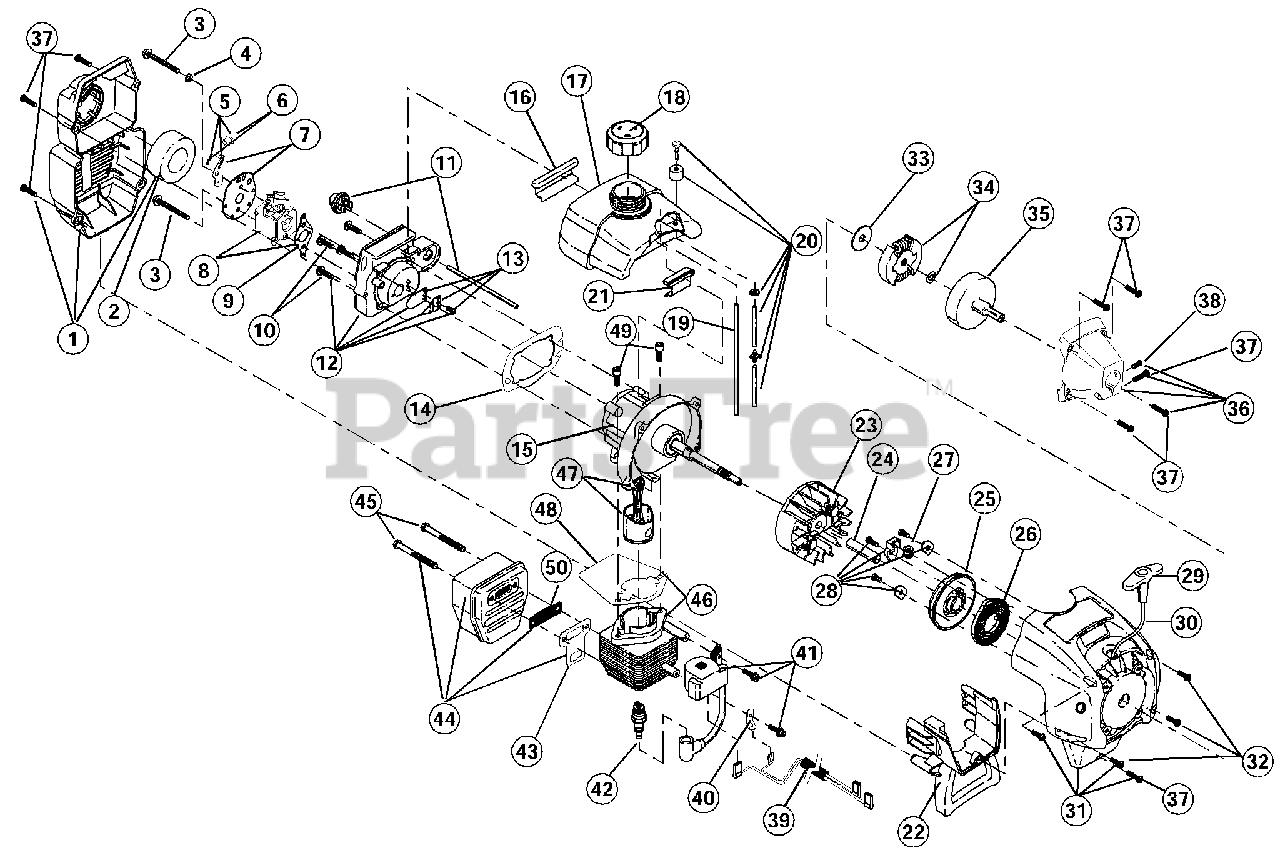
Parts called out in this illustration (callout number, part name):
1	Air Cleaner/Muffler Cover Assembly
2	Air Cleaner Filter
3	Carburetor Mounting Screws
4	Wavey Washer
5	Choke Lever Assembly
6	Choke Knob and Screw
7	Choke Lever and Plate
8	Carburetor Assembly
9	Carburetor Gasket
10	Carb Mount Screw
11	Primer and Hose Assembly
12	Carb Mount Assembly
13	Reed Assembly
14	Carburetor Mount Gasket
15	Crank Case Service Assembly
16	Rear Mounting Pad
17	Fuel Tank Assembly
18	Fuel Cap Assembly
19	Fuel Return Line
20	Fuel Line Assembly
21	Front Mounting Pad
22	Shroud Extension and Stand
23	Flywheel Assembly
25	Recoil Pulley Assembly
26	Recoil Spring
27	Rope Guide
28	Pulley Retainer Assembly
29	Pull Handle
31	Starter Housing Assembly
32	Housing Screw
33	Clutch Washer
34	Clutch Rotor Assembly
35	Clutch Drum Assembly
36	Clutch Cover Assembly
37	Cover Screw
38	Anti-Rotation Screw
39	Wire Leads and Sleeve
40	Ground Tab
41	Module Assembly
42	Spark Plug
43	Exhaust Gasket
44	Muffler Assembly
45	Muffler Mounting Bolt Assembly
46	Cylinder Assembly
47	Piston and Rod Assembly
48	Cylinder Gasket
49	Cylinder Bolt
50	Spark Arrestor Screen
